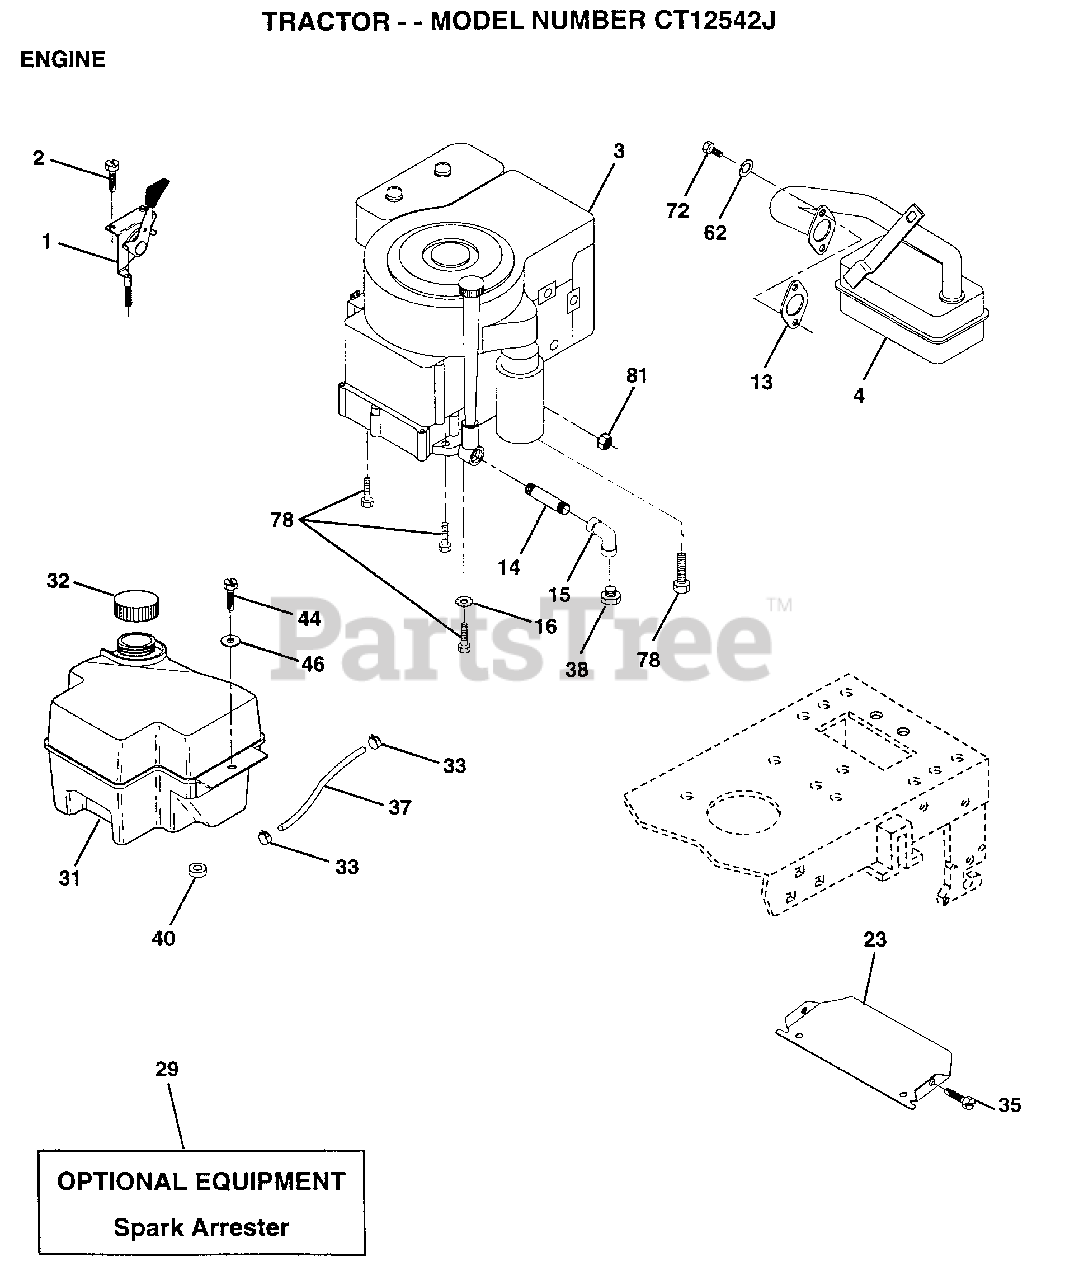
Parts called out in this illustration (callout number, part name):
1	CONTROL THROTTLE
2	SCREW LT
4	MUFFLER
13	GASKET ENG 1 313 LD TIN PLATED
14	PIPE NIPPLE
15	ELBOW
16	LOCKWASHER
18	SHIELD HEAT
19	RECEPTACLE LT
22	"STUD 1/4 TURN,BUS"
24	SCREW
32	CAP ASM FUEL
33	HOSE CLAMP
35	SCREW
37	LINE FUEL
44	SCREW HEX CRT
46	WASHER
62	LOCKWASHER
72	SCREW
78	SCREW
81	NUT
